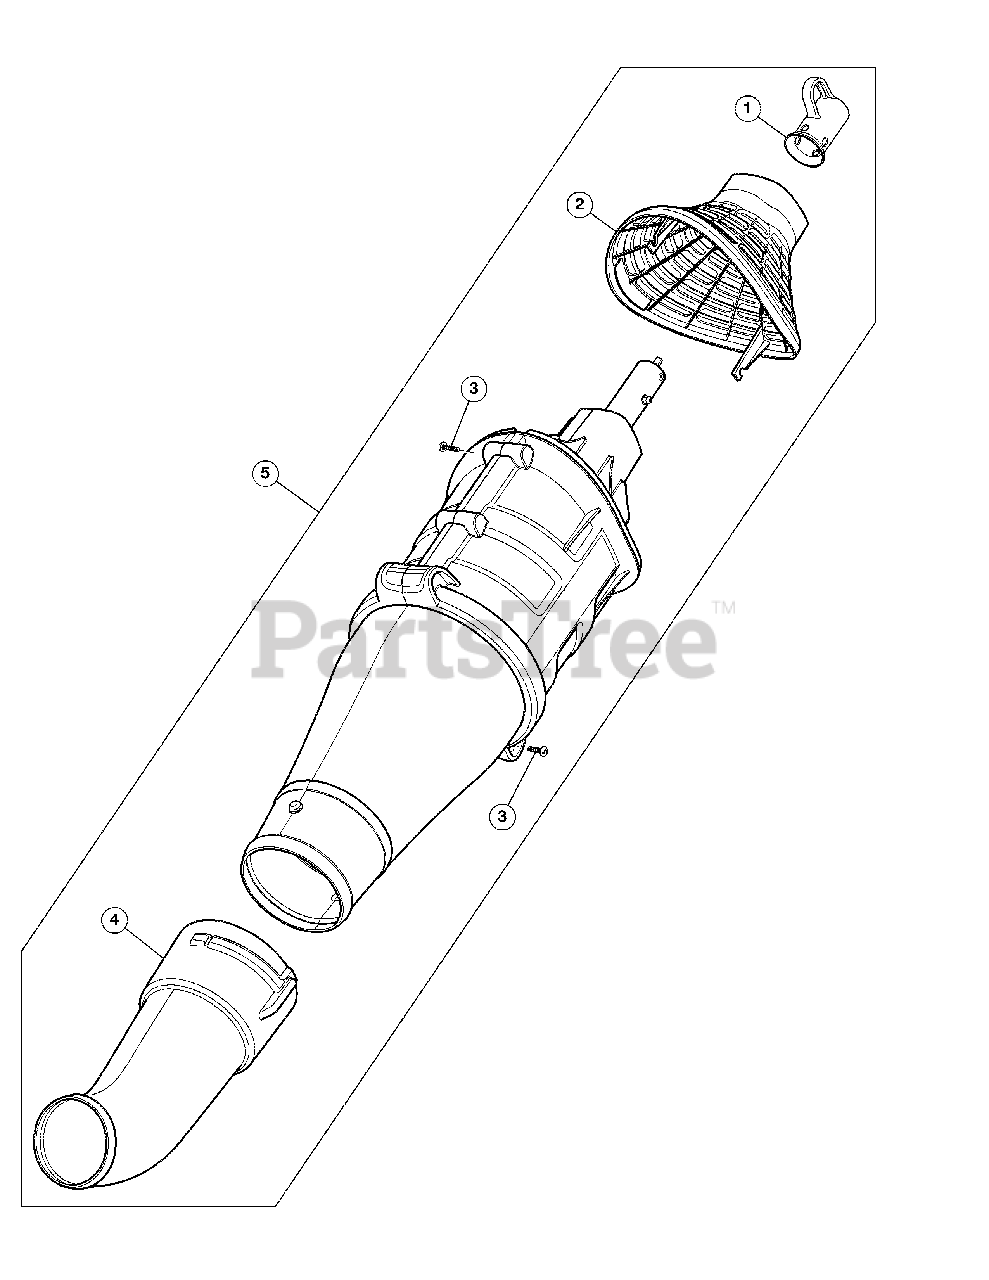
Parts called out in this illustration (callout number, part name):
1	Hanger
2	Blower Intake Housing
4	Blower Nozzle
5	Blower Assembly
